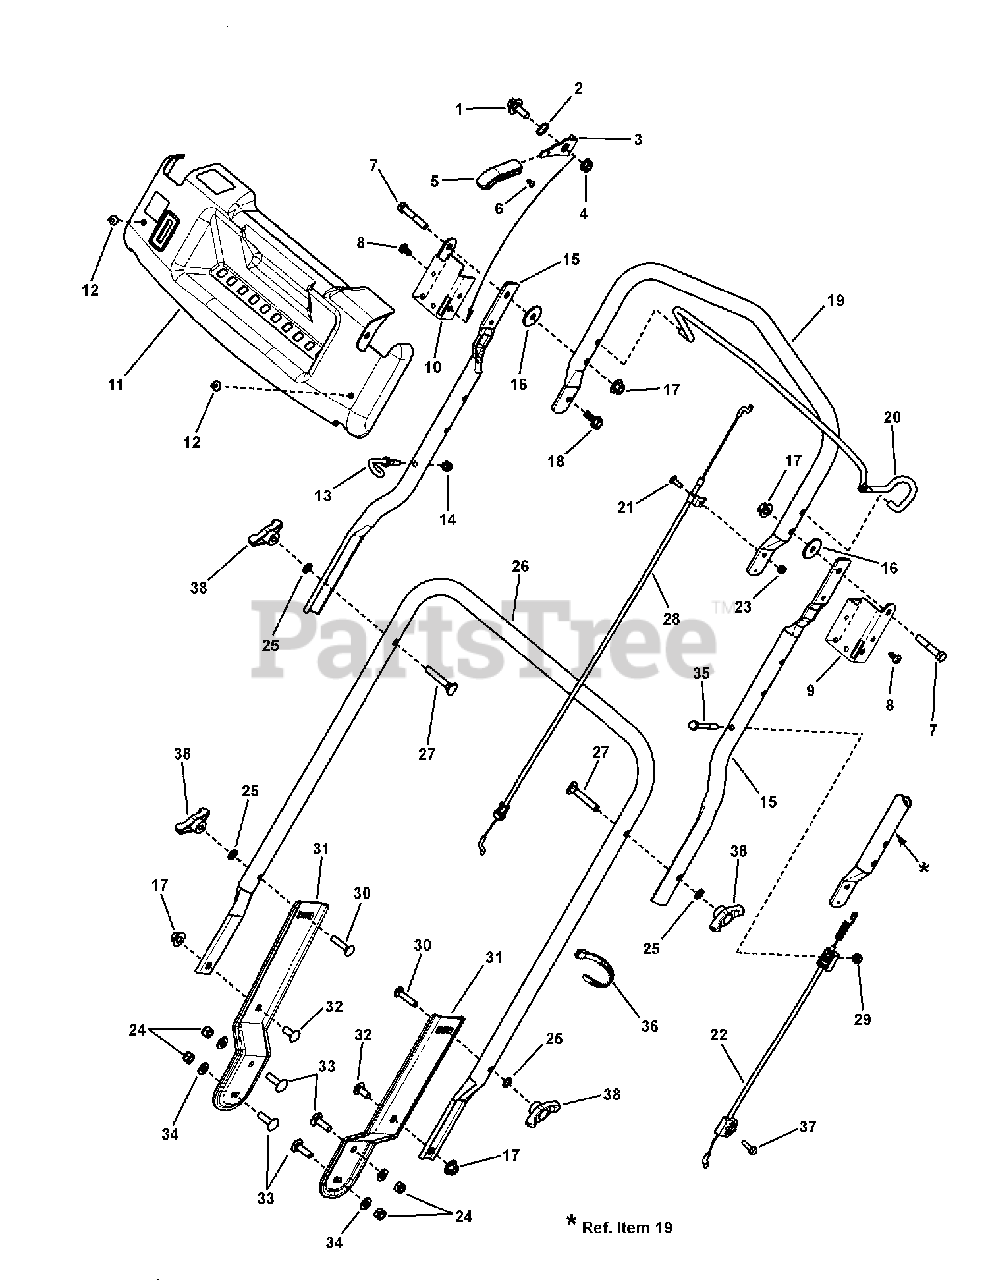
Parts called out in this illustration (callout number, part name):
1	SHOULDER BOLT, 5/16-18
2	WASHER, .531 x .781 3-Wave
3	HANDLE, Lock
4	NUT, 5/16-18 Hex Flange lock
5	LEVER, Throttle Control
6	RIVET, Plastic Snap
7	SCREW, 5/16-18 x 1-3/4 Hex Head Cap, GR 5
8	SCREW, 1/4-20 x 1/2" Pan Head Self-Tap (Torx)
9	BRACKET, LH, Rotation Limit
10	BRACKET, RH, Rotation Limit
11	PANEL, Upper Handle WBM Black
12	RIVET
13	ROPE GUIDE (184-20 thread)
14	NUT, 1/4-20 Hex Nyloc
15	HANDLE, Upper, Pivot
16	WASHER, 5/16 Nylon
17	NUT, 5/16-18 Center Lock (Large Head)
18	SCREW, 5/16-18 x 3/4 WAHH
19	HANDLE Pivot
20	BAIL, Pivot Handle
21	BOLT, #10-24 x 1/2" Flat Head Square Neck
22	CABLE, OPC, Pivot-Handle
23	NUT, #10-24 Hex Nyloc
24	NUT, 5/16-18 Hex Nyloc
25	WASHER, 5/16 Internal Tooth lock
26	HANDLE, Lower
27	SCREW, 5/16-18 x 2" Square Neck Curved Head
28	CABLE, Drive, Pivot-Handle
29	NUT, 1/4-20 Hex Center Lock
30	BOLT, 5/16-18 x 1-1/2" Round Head Square Neck
31	BRACKET, Lower Handle, Alum Deck
32	BOLT, 5/16-18 x 3/4"Round Head Short Square Neck, GR 5 YZ
33	BOLT, 5/16-18 x 1" Round Head Square Neck, GR5
34	FLAT WASHER, .34 x .69 x .08
35	SCREW, 1/4-20 x 2" Hex Head Cap GR 5
36	WIRE TIE, 5.5" Long, Black
37	SCREW, #10-24 x 5/8" Hex Washer Face Self-Tap, GR 5
38	KNOB, 5/16-18 Wing (Black)
